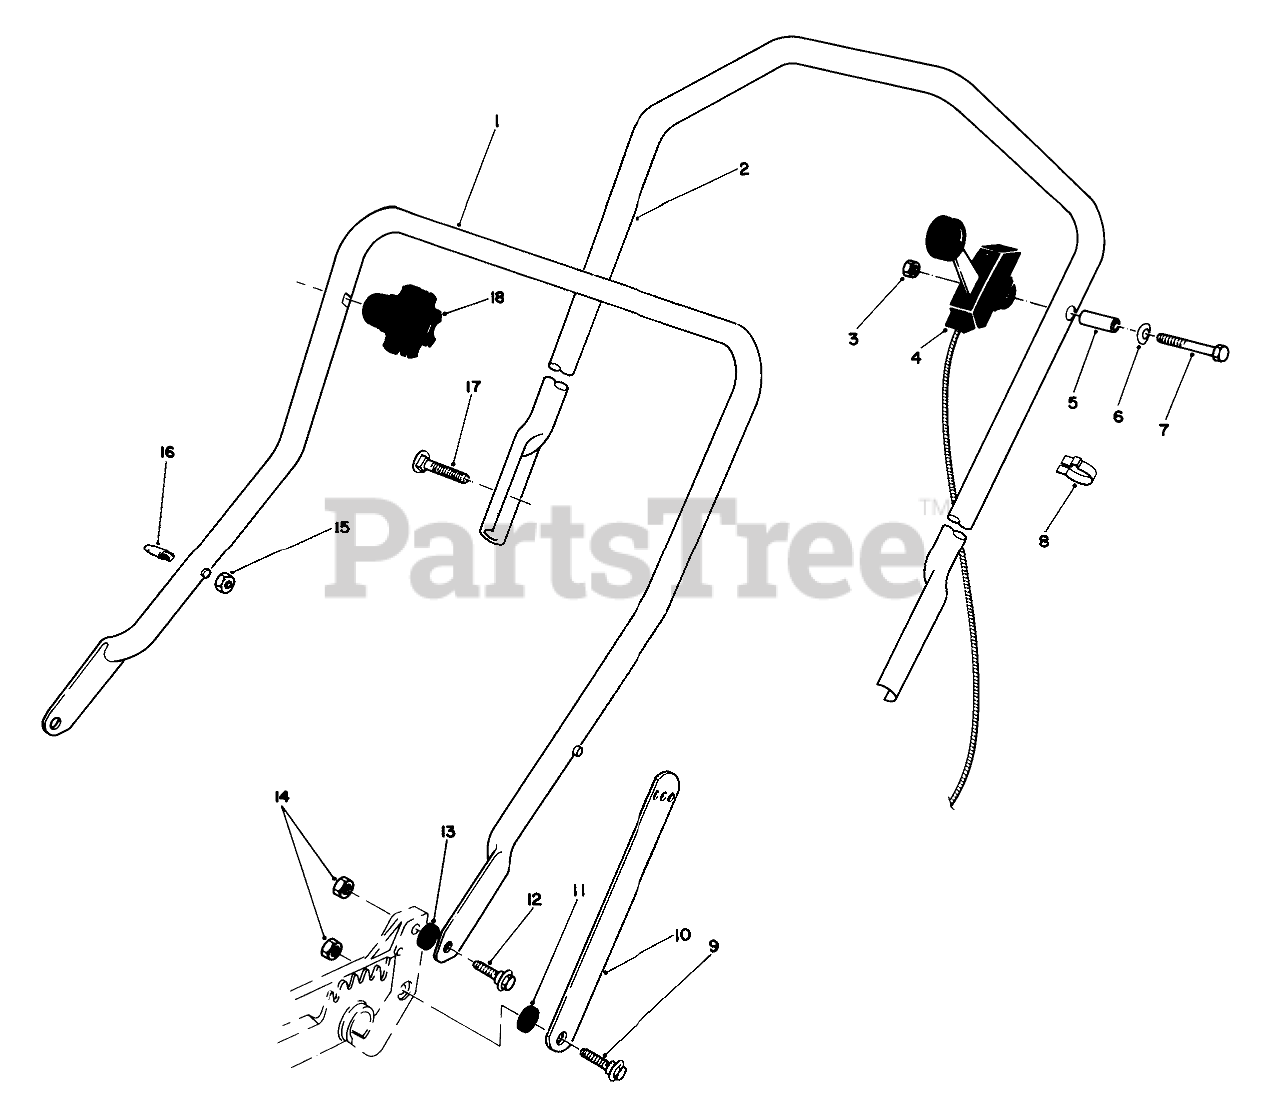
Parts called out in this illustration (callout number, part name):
1	LOWER HANDLE ASM
2	UPPER HANDLE
3	NUT-LOCK, NI
4	SERVICE THROTTLE CONTRO
5	Spacer
6	WASHER
7	SCREW-HH
8	BOWDEN CLIP
9	SCREW-SHOULDER
10	Handle Latch
11	SPACER
12	SCREW-SHOULDER
13	SPACER
14	NUT-LOCK, NI
15	NUT-LOCK, NI
16	HANDLE PIN
17	5/16-18 X 2 HNDLE SCREW
